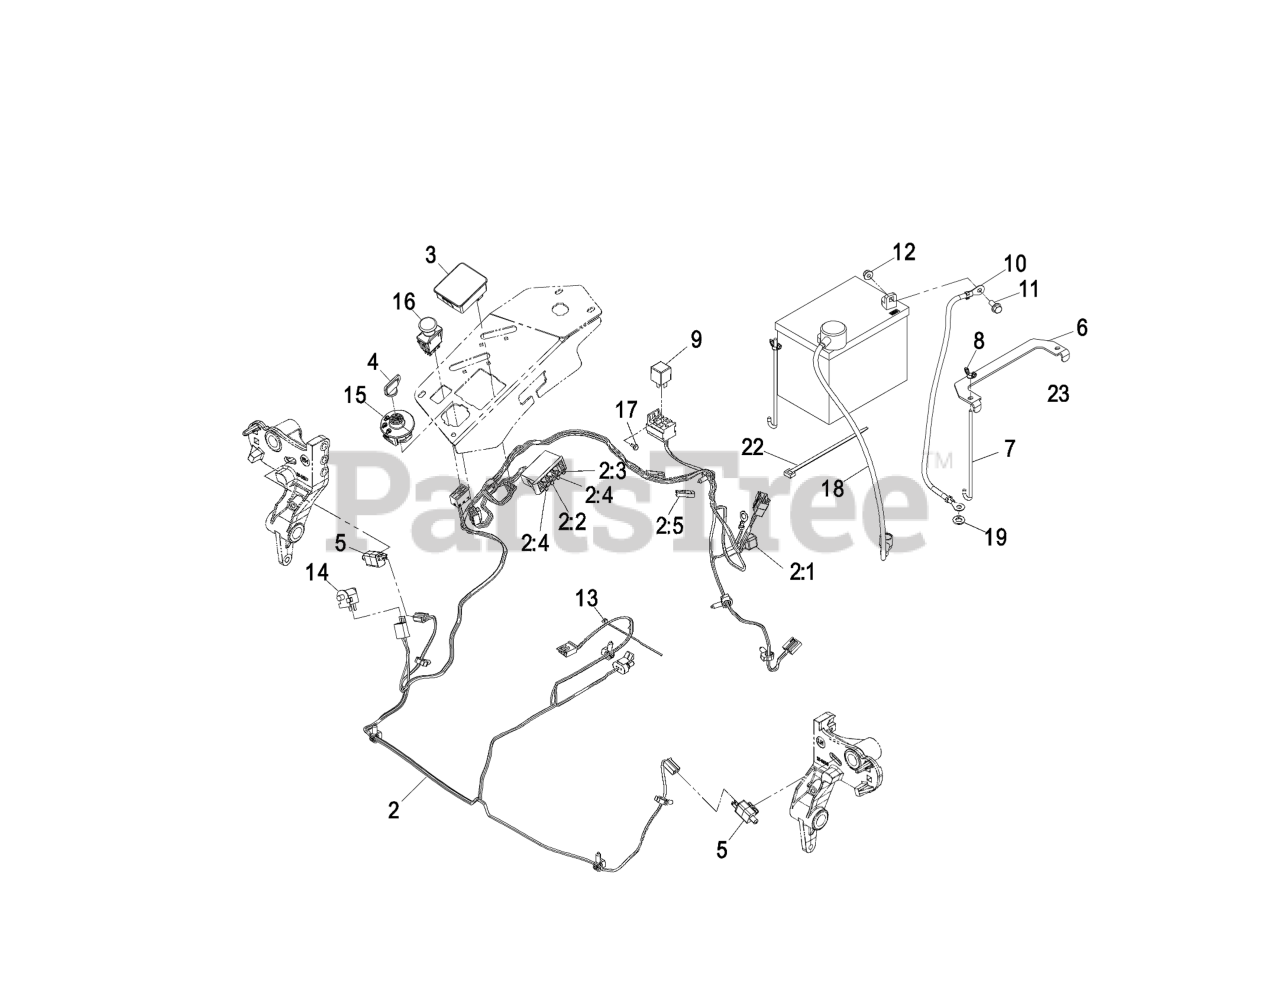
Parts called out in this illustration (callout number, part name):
2:2	FUSE-BLADE, 10 AMP
2:3	FUSE-BLADE, 15 AMP
2:4	FUSE-BLADE, 25 AMP
2:5	CAP-PLUG
4	KEYS-IGNITION (SPARE PAIR
6	STRAP-TIE DOWN, BATTERY
7	BOLT-HOLDDOWN
8	WINGNUT
10	CABLE-BATTERY, NEGATIVE
11	SCREW-HHF
12	NUT-HF, NI
13	TIE-CABLE
14	SWITCH-BAIL
16	SWITCH-PTO, 10 AMP
17	SCREW-HWH
18	CABLE-BATTERY, POSITIVE
19	WASHER-FLAT
22	TIE-PLASTIC
